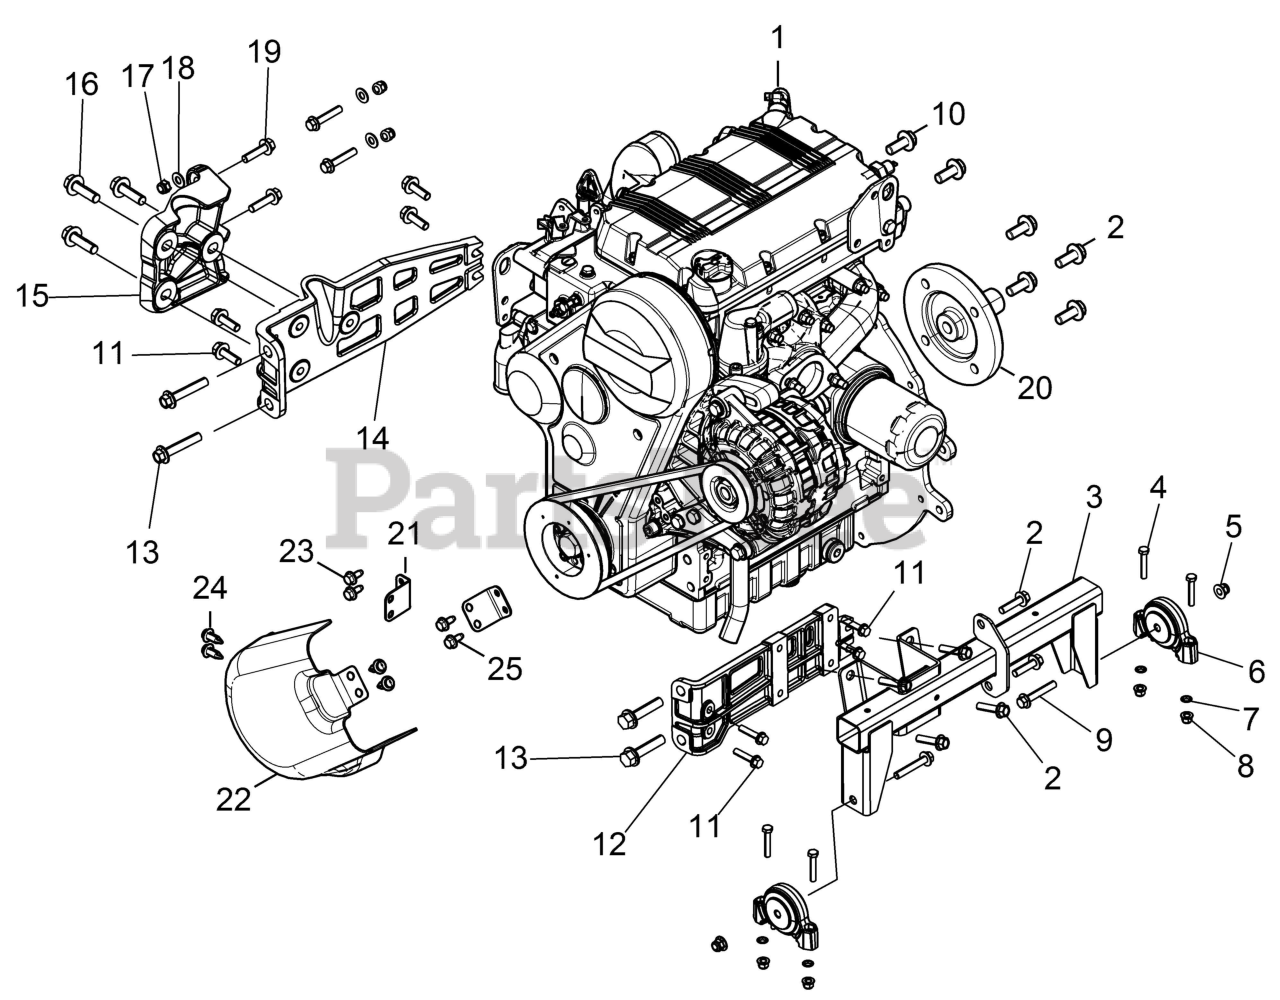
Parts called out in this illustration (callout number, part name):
1	ASM-ENG KDW1003-5143
2	SCR-M10X1.5X25 8.8 HXFL ZOD
3	WELD-MOUNT,ENGINE,BLK
4	SCR-HH M8X1.25X45 8.8 ZOD
5	NUT-M10X1.25,FLG,NYLOC-OLIVE D
6	MOUNT-ISOLATOR,DRIVELINE
8	NUT-M8X1.25,FLG,NYLOC-OLIVE D
9	BOLT-M10X1.25X60,HXFLG-OLIVE D
10	SCR-HXFL-M8X1.25X20 8.8 ZOD P3
11	BOLT-M8X1.25X25,HXFLG-OLIVE D
12	COUPLER-L-ENGINE,FRONT
13	SCR-HXFL-M12X1.75X30 ZOD
14	COUPLER, ENGINE, GEARCASE
15	COUPLER-L-ENGINE,GEARCASE
16	SCR-HXFL-M10X1.5X35 10.9 ZOD D
17	NUT-M10X1.5 HFN NYLOC ZOD
18	WASHER,3/8 FW
19	SCR-HXFL-M10X1.5X50 10.9 ZOD
20	ADAPTER-CLUTCH,DSL
21	BRKT,BELT GUARD,MOUNT,BLK
22	COVER,DEBRIS
23	BOLT,M6X1.0X15,HXFLG,TAP/T-OD
24	RIVET-TUFLOK,.315-.325X.787 (5
